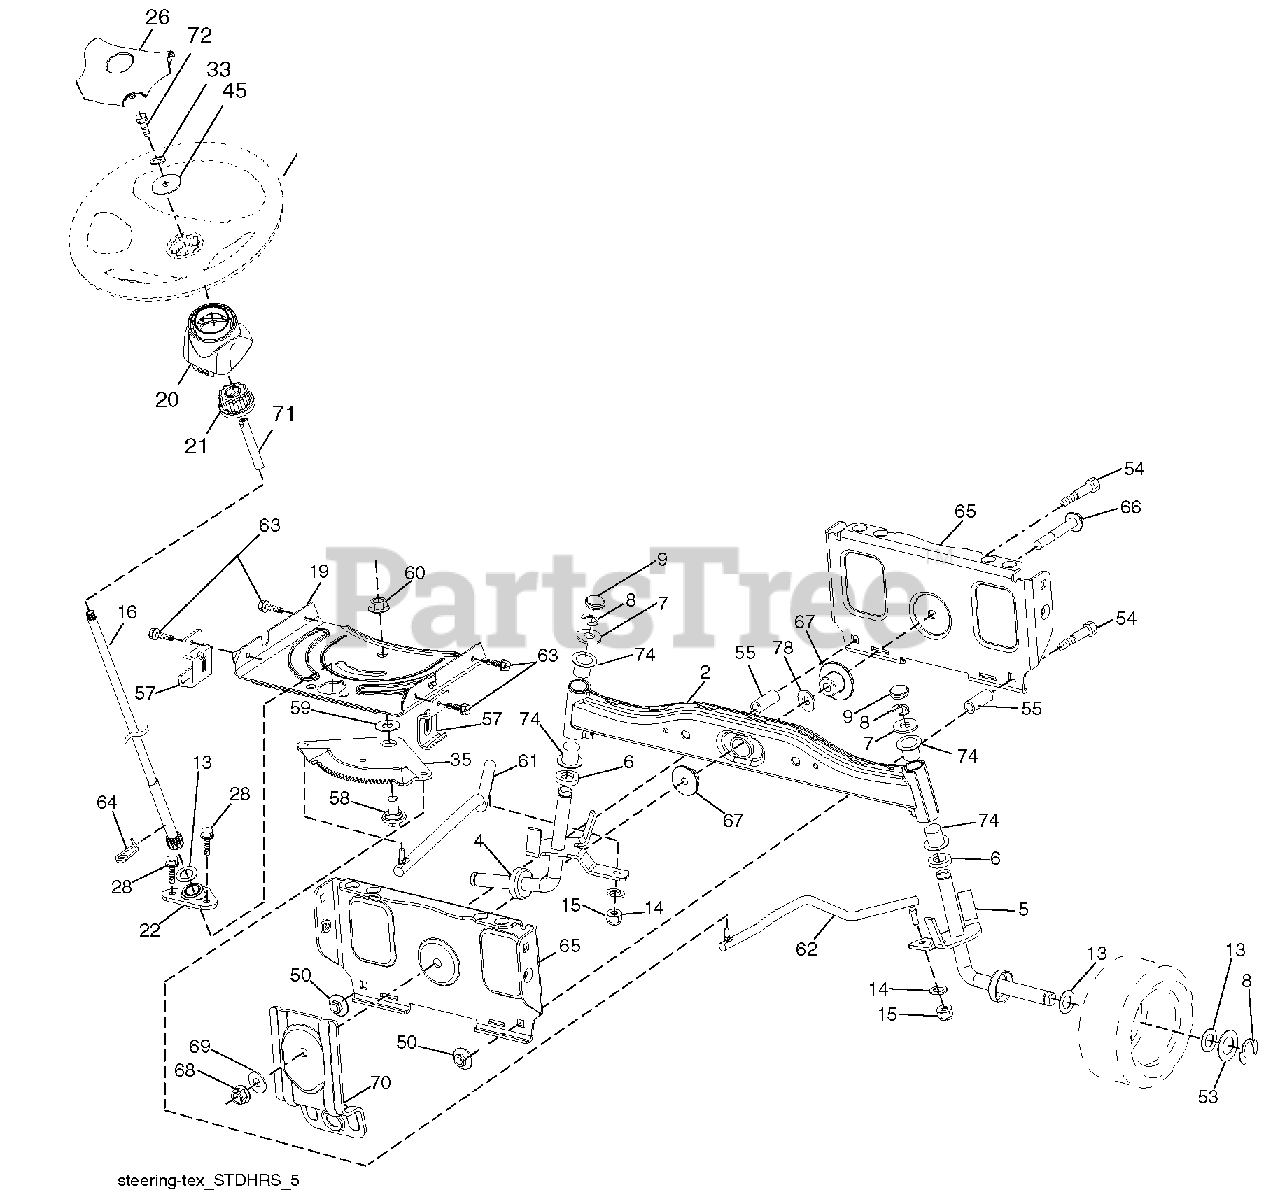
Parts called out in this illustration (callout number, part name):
1	Wheel, Steering
2	Axle Asm., Front
4	Spindle Asm., LH
5	Spindle Asm., RH
6	Thrust Washer
7	Washer 25/32 x 1-5/8 x 16 Ga.
8	Ring, Clip #T5304-75
9	Cap, Spindle
13	Washer 25/32 x 1-1/4 x 16 Ga.
14	Washer Lock 3/8
15	Nut, Crown Lock 3/8-24 unf
16	Shaft Steering
19	Plate Steering
20	Boot, Steering
21	Adapter, Wheel Steering
22	Bushing, Strg. Blk
26	Insert, Wheel Steering
28	Screw 3/8-16 x 3/4
33	Washer Lock 5/16
35	Gear, Sector Plate
45	Washer 11/32 x 2-3/8 x 12 Ga.
50	Nut Lock Flg 3/8-16 unc
53	Washer Hardened .793 x 1.637 x .060
54	Bolt Hex HS 3/8-16 unc x 2-1/4
55	Spacer Brace Axle
57	Bracket Upstop
58	Bolt Shoulder Sector Pivot CFM
59	Washer Thrust Sector Steering
60	Nut Flange Lock 5/8-11
61	Draglink, LH
62	Draglink, RH
63	Screw 5/16-18 x 3/4
64	Retainer Clip Spring Steering
65	Brace Axle Front
66	Bolt Hex Fghd 7/16-14 x 3 Serr
67	Bushing PM Front Axle
68	Nut Lock Flange 7/16-14 Gr. 5
69	Washer 1.5 x .505 x .118
70	Bracket Deck Susp. Front
71	Shaft Ext. Steering
72	Bolt 5/16-18 x 4.5 Gr. 5
74	Bearing Colstrg Blk.
78	Washer Thrust .515 x .750 x .033
